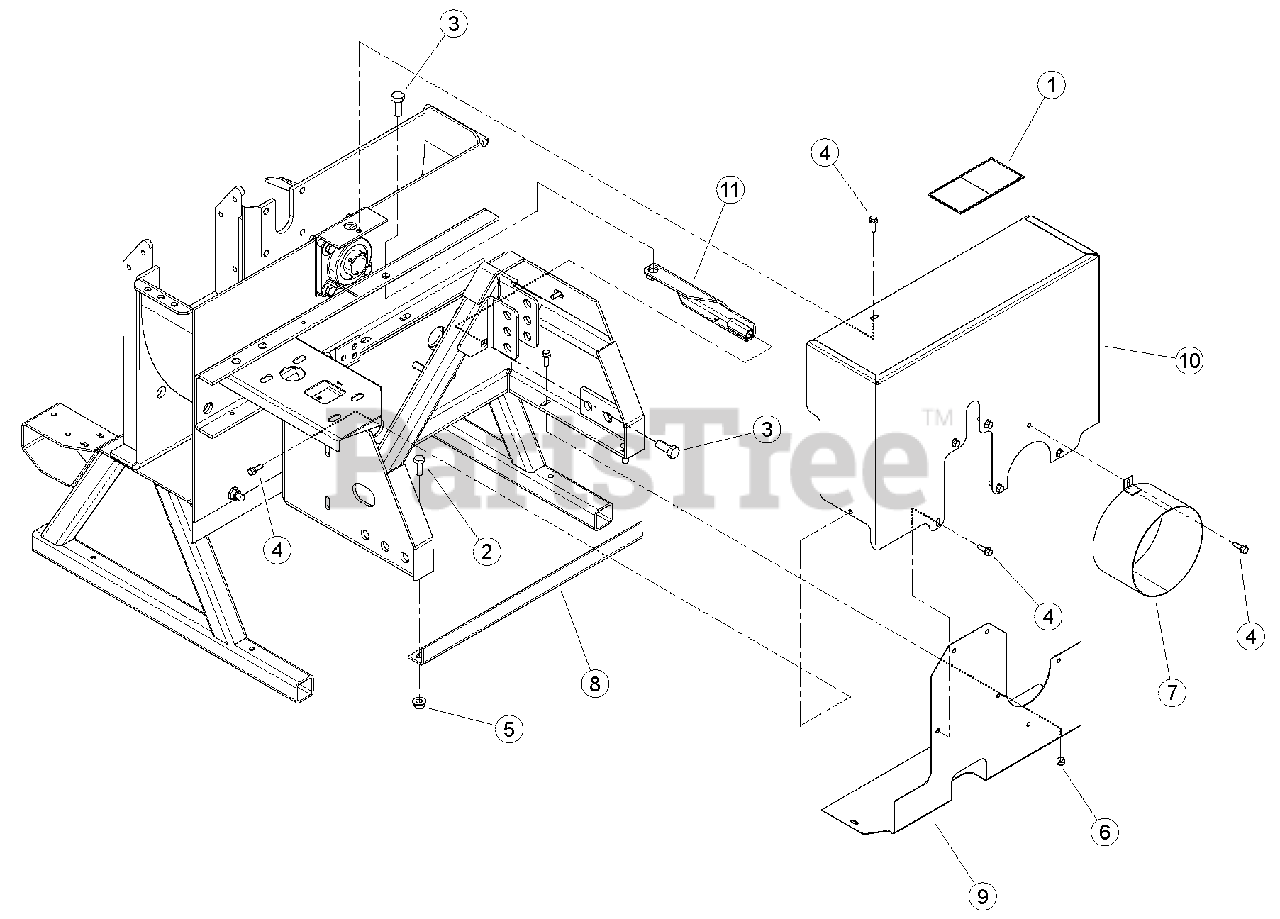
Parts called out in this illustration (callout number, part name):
1	DECAL, PTO DANGER ISO
2	BOLT, 1/2 X 1-1/4" GR5 HHCS NC ZP
3	BOLT, 5/8 X 1-1/2 HEX HD GR5 ZP
4	BOLT, 5/16 X 1 FLANGE NC
5	NUT, 1/2-13 NYLOCK FLANGE
6	NUT, 5/16-18 NYLOCK FLANGE
7	WELDMENT, PTO SHIELD
8	BRACE, 3 PT BOTTOM
9	WELDMENT, GUARD PTO LOWER BELT
10	WELDMENT, GUARD PTO UPPER BELT
11	WELDMENT, BRACE PTO 3-POINT
